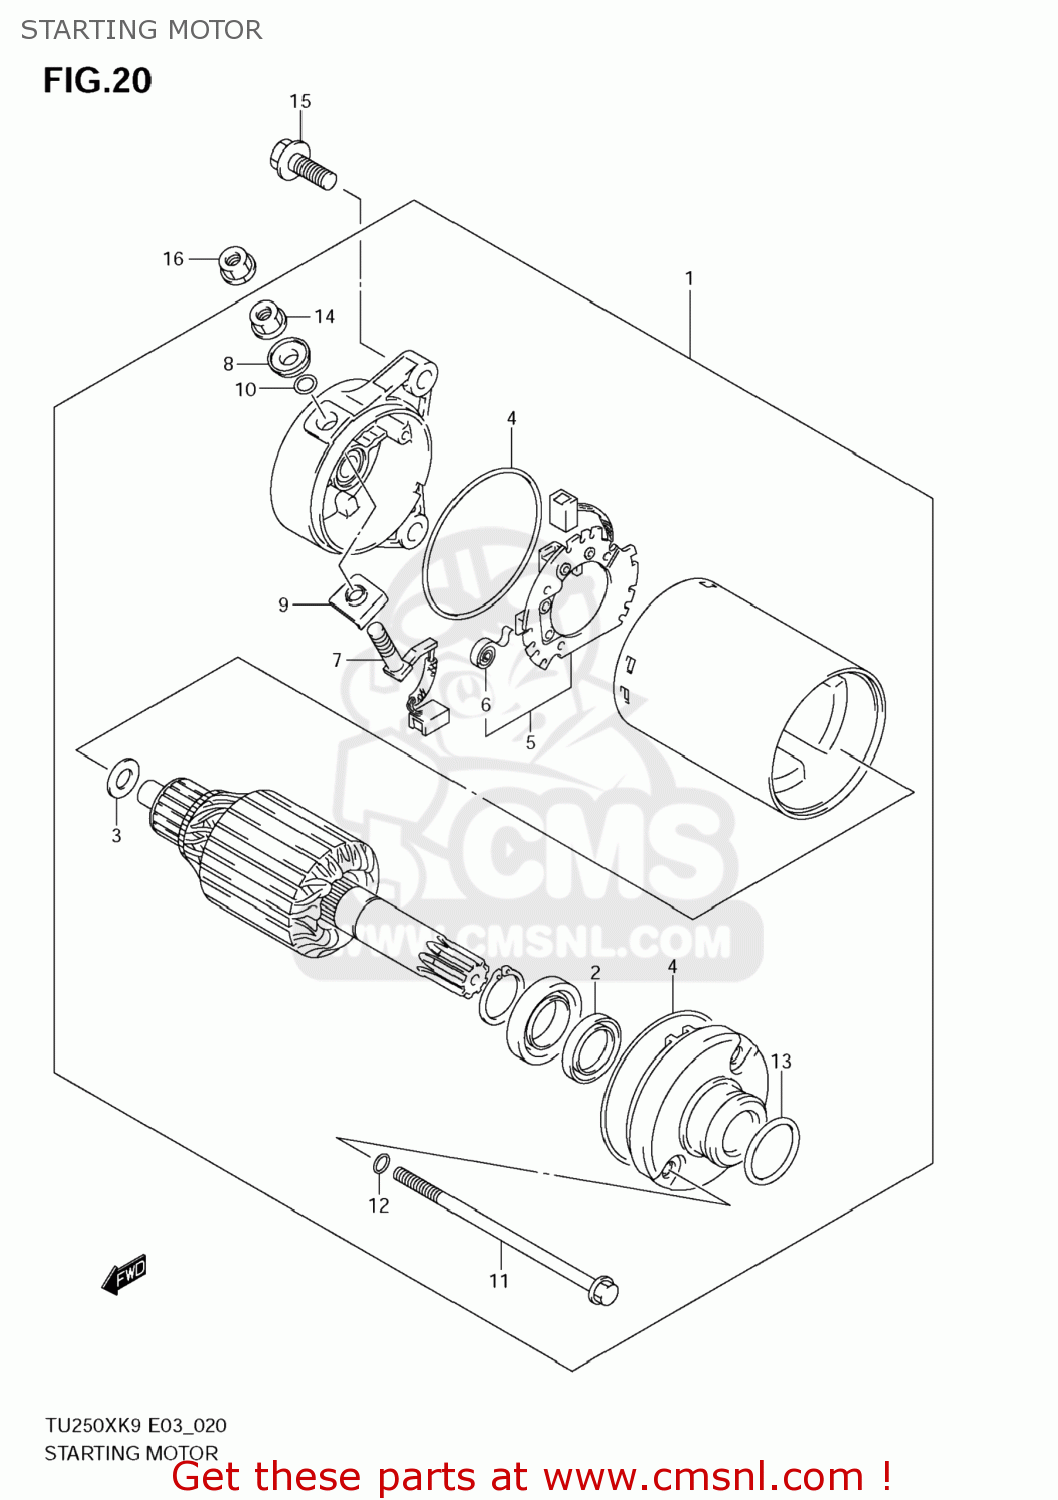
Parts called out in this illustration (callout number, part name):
1	MOTOR ASSY,STARTING
2	SEAL,OIL
3	SHIM SET,STARTING MOTOR
4	O RING
5	HOLDER,BRUSH
6	SPRING
7	BRUSH SUB ASSY,STARTING MOTOR
8	BUSHING
9	BUSH,B
10	O RING
11	BOLT
12	O RING
13	O RING(D:3,ID:24.5)
14	NUT
15	BOLT(6X25)
16	NUT
